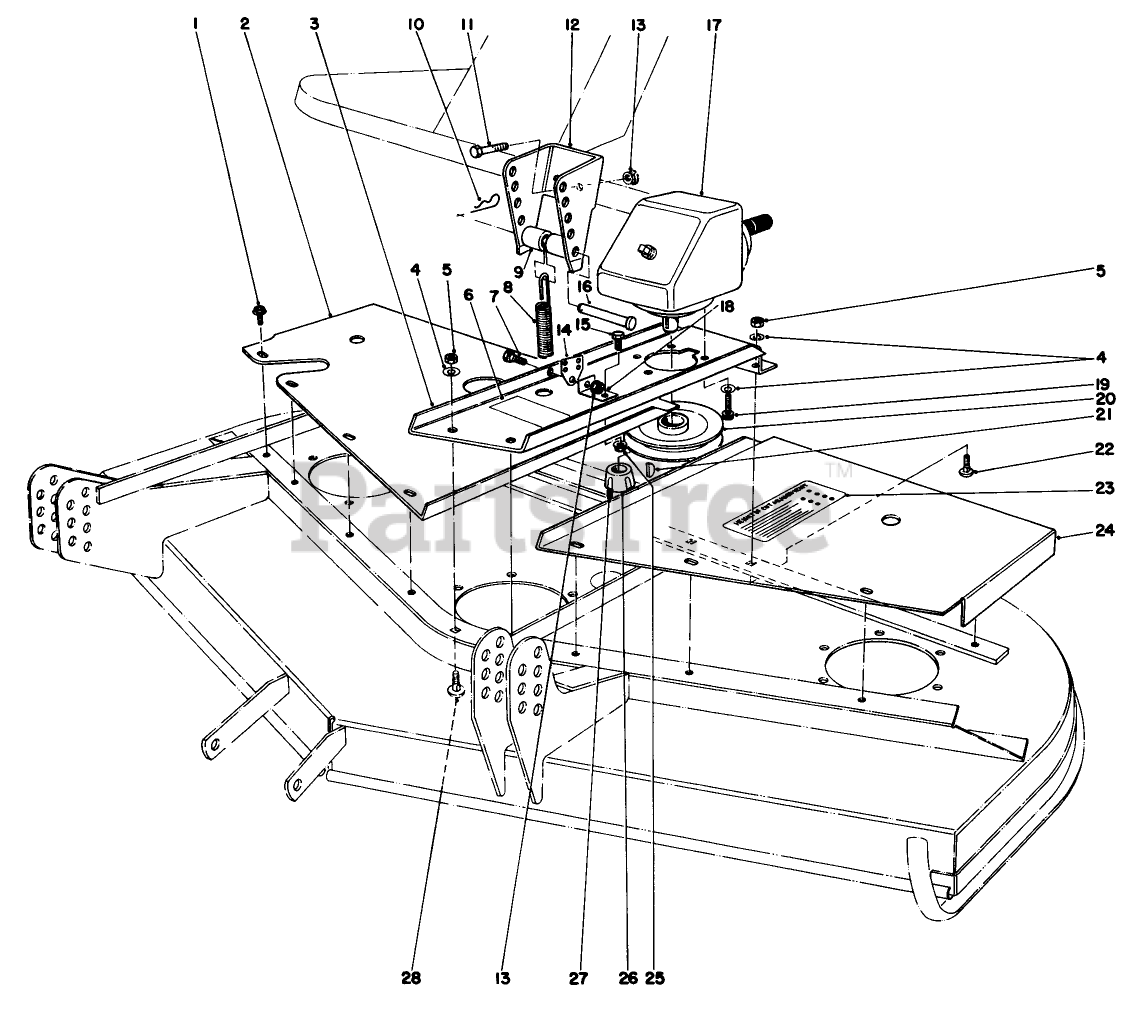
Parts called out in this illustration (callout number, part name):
1	SCREW-HHFTF
2	RH COVER WA *R
4	WASHER-LOCK
5	NUT-HEX
7	BOLT-SHOULDER
9	SPACER
10	PIN-HAIR
11	SCREW-HH
12	SPRING BRACKET *R
13	NUT-HHF, WHIZ
15	SCREW-HH
16	PIN-CLEVIS
18	EXTENSION BRKT *R
19	SCREW-HSH
21	KEY-WOODRUFF
22	SCREW-HH
24	LH COVER WA *R
25	NUT-HF
26	BUSHING-LOCK, TAPER
27	SCREW-SET, HSH
28	SCREW-CARR
